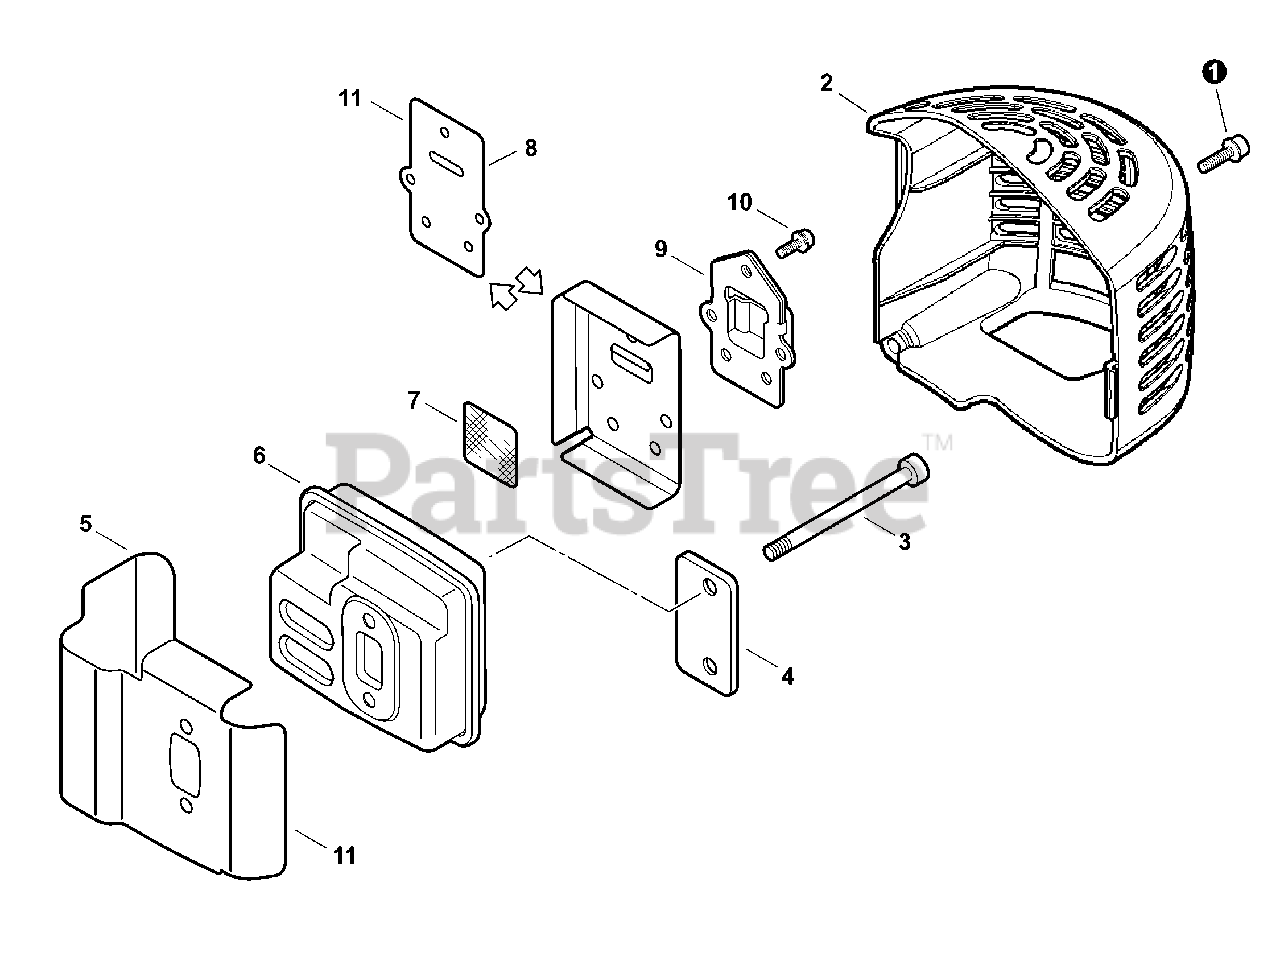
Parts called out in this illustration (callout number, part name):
1	SCREW - 5×16
2	COVER, EXHAUST
3	SCREW - 5×55
5	SHIELD, EXHAUST
6	MUFFLER
7	SCREEN, SPARK ARRESTOR
8	GASKET, EXHAUST
9	GUIDE, EXHAUST
10	SCREW - 4×10
11	GASKET KIT
